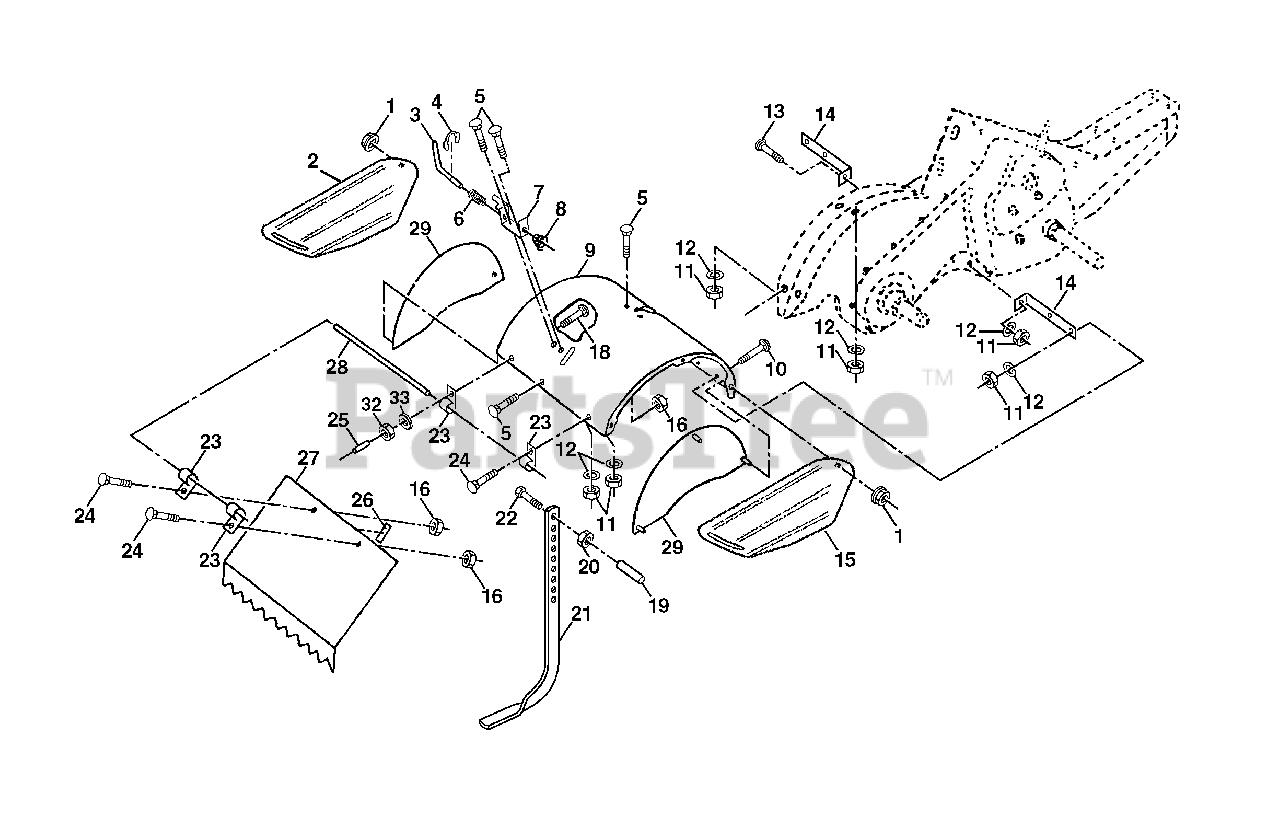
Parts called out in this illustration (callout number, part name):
1	Nut, Flange 5/16-18
2	Shield, Side, Outer L. H.
3	Pin, Stake, Depth
4	Ring, Klip
5	Bolt, Carriage 5/16-18 x 3/4 Gr 5
6	Spring
7	Bracket, Latch
8	Spring, Depth Stake
10	Bolt, Carriage 5/16-18 x 1
11	Nut, Hex 5/16-18
12	Washer, Lock 5/16
13	Bolt, Carriage 5/16-18 x 1-1/4
14	Bracket, Shield Tine
15	Shield, Side, Outer R.H.
16	Nut, Hex Flange 1/4-20 UNC
18	Bolt, Carriage 1/4-20 x 1-1/4 Gr. 5
19	Grip
20	Nut, Hex 3/8-16
21	Stake, Depth
22	Bolt, Hex 3/8-16 x 2
23	Hinge
24	Bolt, Carriage 1/4-20 x 1/2 Gr. 5
25	Cap, Vinyl
26	Pad, Idler
27	Shield, Leveling
28	Pin, Hinge
32	Nut Fin Hex 1/4-20 UNC
33	Washer Lock Hvy Helical 1/4
